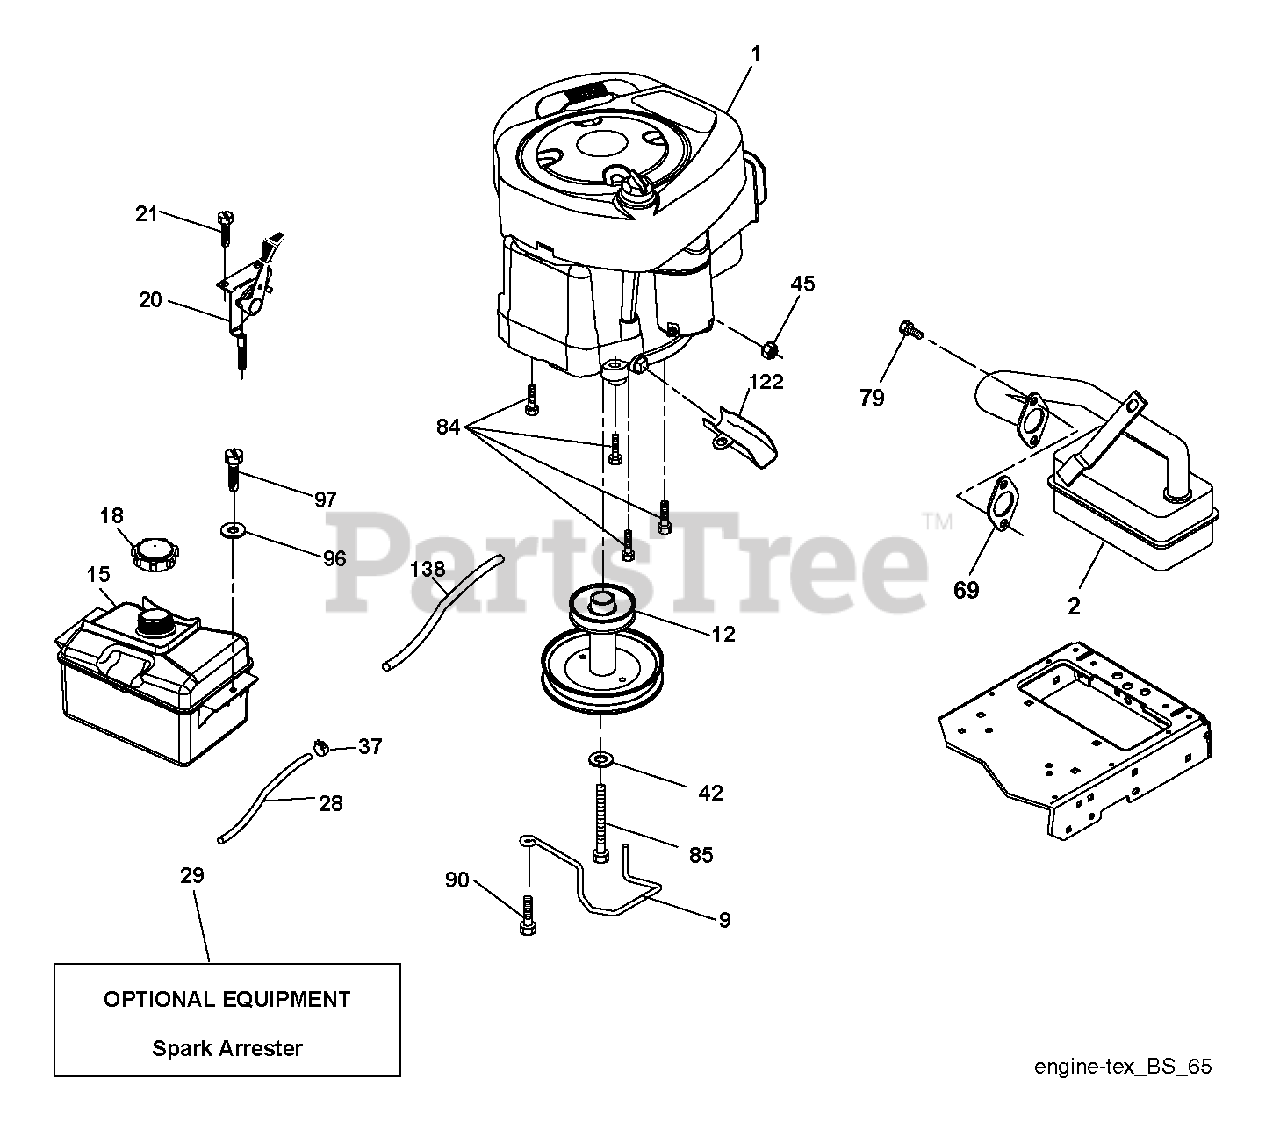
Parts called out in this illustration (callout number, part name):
2	MUFFLER.LT.BRIGGS.14HP.IC/OHV
9	KEEPER.BELT.ENGINE.3.25
12	PULLEY ENGINE
15	TANK.ASM.1.5GAL.FRT.W/CAP.EPA
18	CAP.2.25'.VENTED.RATCHET.EPA
21	SCREW.#10 X 0.750.BOS (2 2)
28	LINE.FUEL.20"FRONT.EMI
29	KIT.SPARK ARRESTOR(392390 B&S)
37	HOSE CLAMP
42	LOCKWASHER
45	NUT
79	SCREW.SOCKET HD.5/16-1
84	SCREW.3/8-16
85	BOLT HEX 7/16-20X4-1/4"
90	SCREW 3/8-16X1
97	SCREW HEXWSHR 1/4-20X3/4
122	EXTENSION DRAIN OIL
138	RP PURGE LINE
